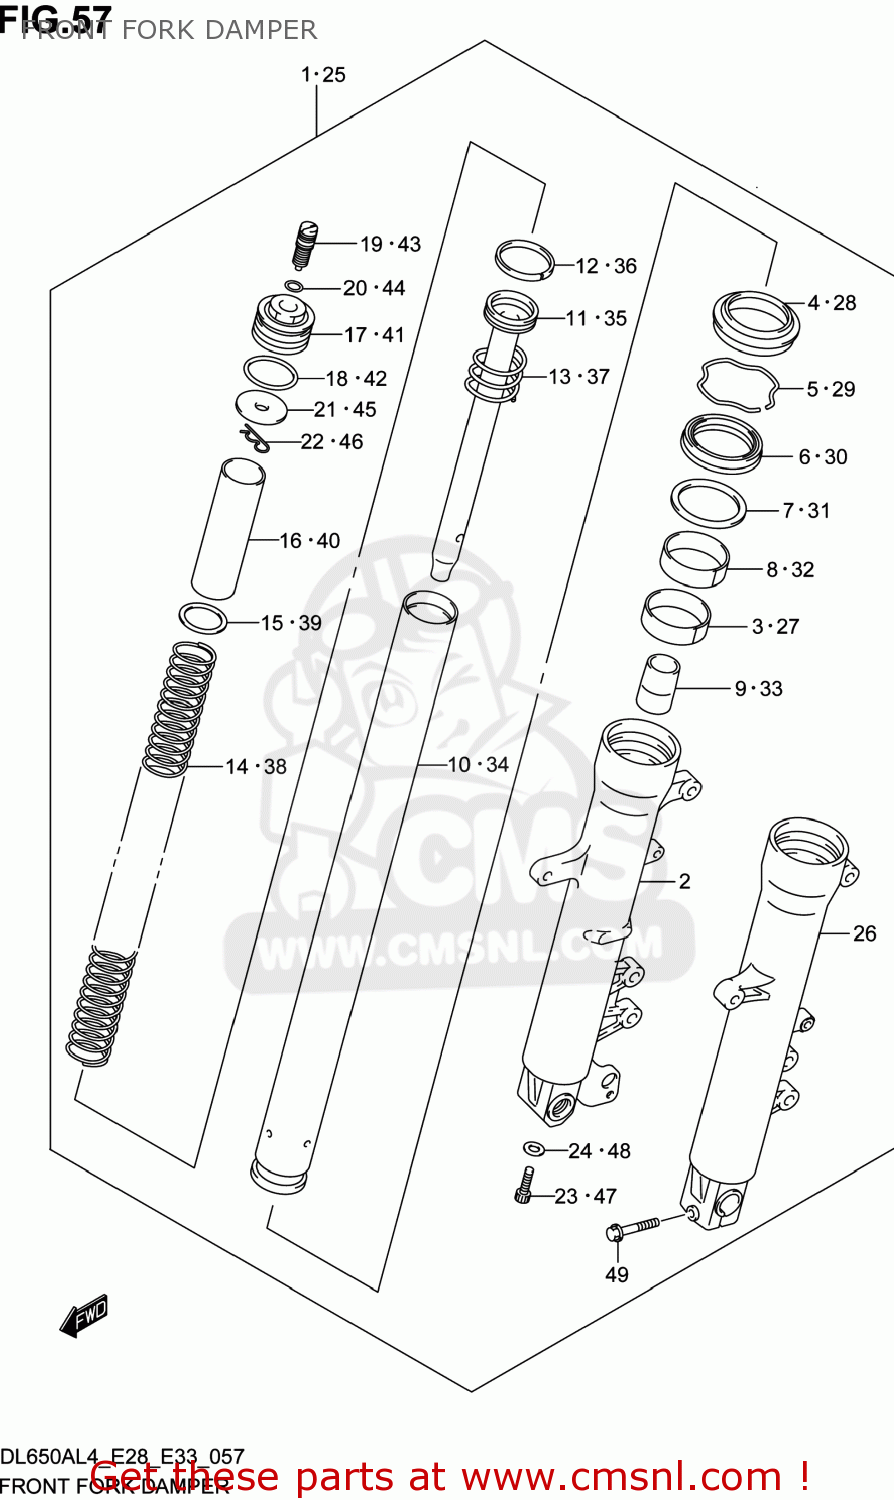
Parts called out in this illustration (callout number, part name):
1	DAMPER ASSY,FR FORK,R
2	TUBE,OUTER,R
3	BUSH,SLIDE
4	SEAL,DUST
5	CIRCLIP,FORK OIL SEAL
6	SEAL,OIL
7	SPACER,SEAL
8	BUSH,GUIDE
9	PIECE,OIL LOCK
10	PIPE,FORK
11	PIPE,SEAT
12	RING,PISTON
13	SPRING,REBOUND
14	SPRING,FR
15	SEAT,SPRING LWR
16	COLLAR,SPRING
17	BOLT,FORK
18	O RING
19	ADJUSTER BOLT,SPRING
20	O RING
21	SEAT,SPRING
22	PIN,SEAT SPRING
23	BOLT(8X27)
24	GASKET (NAS)
25	DAMPER ASSY,FR FORK,L
26	TUBE,OUTER,L
27	BUSH,SLIDE
28	SEAL,DUST
29	CIRCLIP,FORK OIL SEAL
30	SEAL,OIL
31	SPACER,SEAL
32	BUSH,GUIDE
33	PIECE,OIL LOCK
34	PIPE,FORK
35	PIPE,SEAT
36	RING,PISTON
37	SPRING,REBOUND
38	SPRING,FR
39	SEAT,SPRING LWR
40	COLLAR,SPRING
41	BOLT,FORK
42	O RING
43	ADJUSTER BOLT,SPRING
44	O RING
45	SEAT,SPRING
46	PIN,SEAT SPRING
47	BOLT(8X27)
48	GASKET (NAS)
49	BOLT,HOLDER AXLE(8X40)
